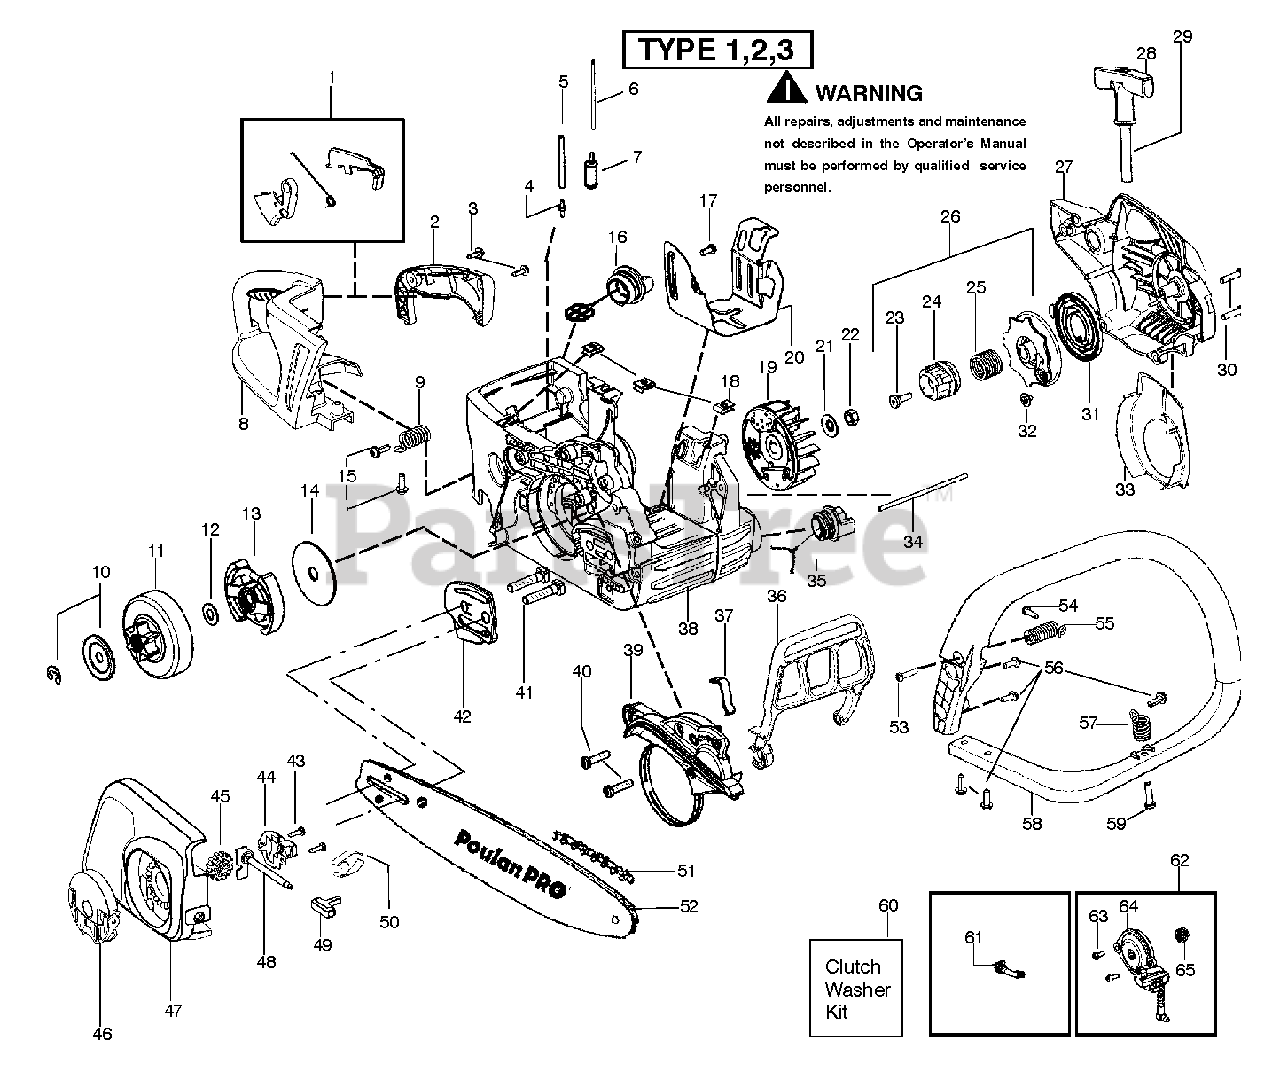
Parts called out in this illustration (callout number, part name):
1	KIT SAV TRIGGER & LOCKOUT
2	COVER HANDLE PPR GOLD OVERMOLD
4	FUEL LINE FITTING
5	LINE KIT
6	KIT-LINE
7	ASSY FUEL PICK UP W/LINE
8	HANDLE REAR PPGOLD OVERMOLD
9	SPRING ISOLATOR
10	KIT SAS CLUTCH WASHER
11	ASSY CLUTCH DRUM 3/8
12	KIT SAS CLUTCH WASHER
13	ASSY CLUTCH
14	WASHER CLUTCH LARGE
15	SCREW,FRONT HBAR 36/41
16	TANK CAP
19	ASSY FLYWHEEL
20	SHIELD HEAT
21	WASHER-FLYWHEEL
22	NUT-FLYWHEEL
23	SCREW SHOULDER
24	HUB STARTER EPS
25	SPRING EPS
26	KIT EPS STARTER
27	Fan Housing
28	HANDLE STARTER
29	KIT-ROPE
30	SCREW M5.38-14X22.225MM
33	BAFFLE FLYWHEEL
34	ASSEMBLY-OIL-VENT
35	OIL TANK CAP
36	HANDGUARD CHAIN BRAKE
37	SPRING HANDGUARD
38	Chassis Assembly, Black with Retainer
39	KIT CHAIN BRAKE
40	SCREW M5.38-14X22.225MM
42	PLATE BAR MOUNTING
45	Thumb Wheel Assembly, SRS Red
46	ASSY EZT KNOB PRO GOLD
47	HSG CLUTCH CVR EZT AV PRO GOLD
48	ADJUSTING SCREW
49	CHAIN TENSIONER PIN
51	ACCY-PLN CHN 16" 91VJ 56DL 3/8
52	BAR 16" SN 91 3/8 56DL
53	SCREW M5.38-14X22.225MM
54	M5.0X0.8X16 TT TRX SEMS
55	SPRING ISOLATOR ASSEMBLY
56	SCREW,FRONT HBAR 36/41
58	HANDLE FRONT
59	SCREW M5.38-14X22.225MM
60	KIT SAS CLUTCH WASHER
61	ASSY PICK UP OIL TANK
62	KIT OIL PUMP
64	ASSY OIL PUMP
65	WORM GEAR
